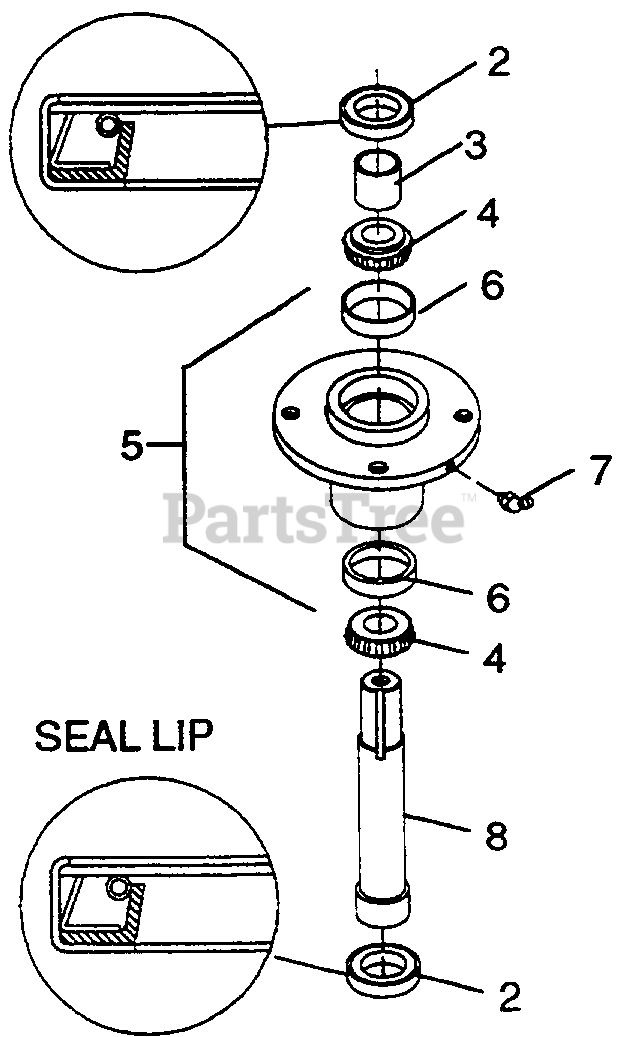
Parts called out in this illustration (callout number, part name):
2	Seal, .063 x 2.004 x 1.125
3	Sleeve, 27/32 x 1-1/16 x 11/16
4	Bearing cone #M12649
5	Spindle, housing with cups
6	Bearing Cup #M12610
7	1/4 Tapered thread 45°
8	Spindle shaft, right hand threads, 1.06 x 5.18
